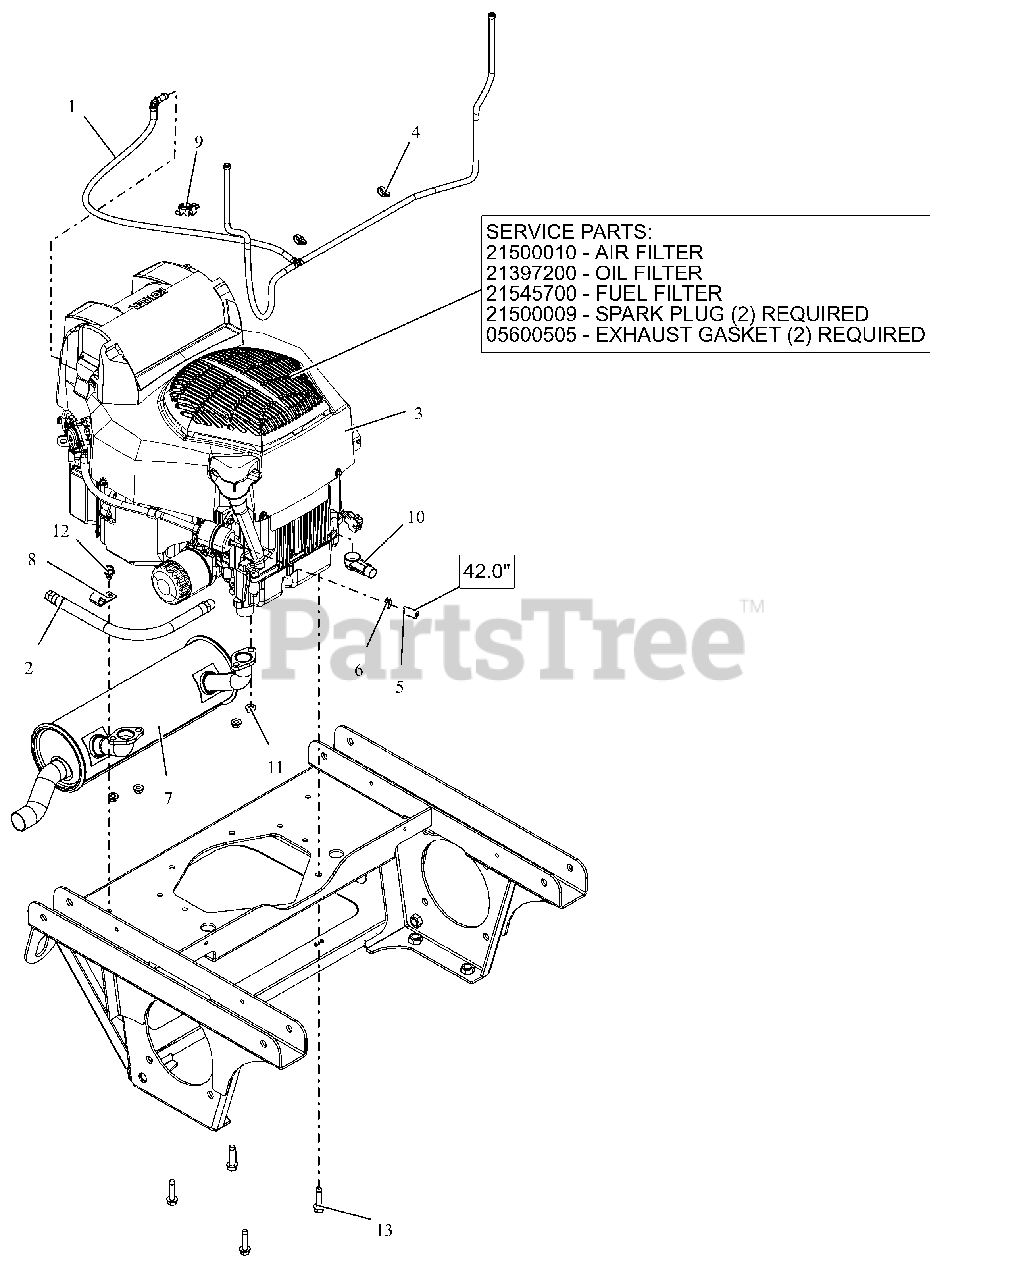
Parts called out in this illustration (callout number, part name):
1	ASM, VAPOR LINE
2	HOSE, OIL DRAIN
3	ENGINE, KOHLER ZT740 CONFIDANT
3	AIR CLEANER, KOHLER CONFIDANT
3	FILTER, OIL - KOH CV20
3	FILTER-FUEL KOHLER COURAGE PRO
3	PLUG, SPARK KOHLER
3	GASKET, MUFFLER KOHLER TWIN
4	ROUTING CLIP (1/2" ID)
5	HOSE, .25 LOW-PERM BULK GAS
6	CLAMP, FUEL LINE
7	MUFFLER, ZT730/ZT740
9	CLIP, T, .38-.50
10	BOOT, .65ID POS
11	NUT-LK-TOP-FLG M8 ZCC
12	SCR,TAP .375-16X.50 HWH TR ZCC
13	SCR-TAP .38-16X1.50 HWH ZCC
